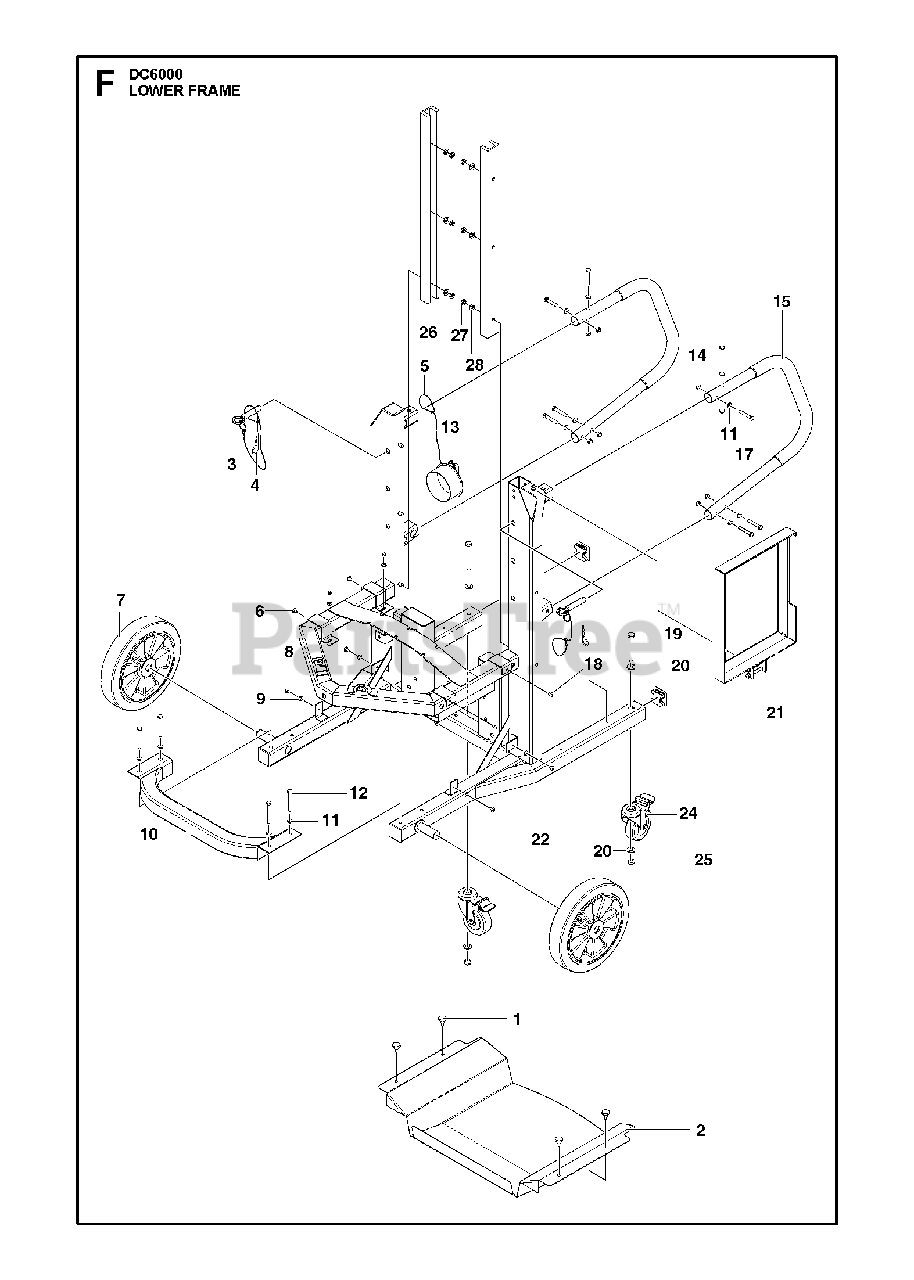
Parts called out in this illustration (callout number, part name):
11	WASHER
14	HEXAGON LOCKING NUT
20	WASHER
28	WASHER
